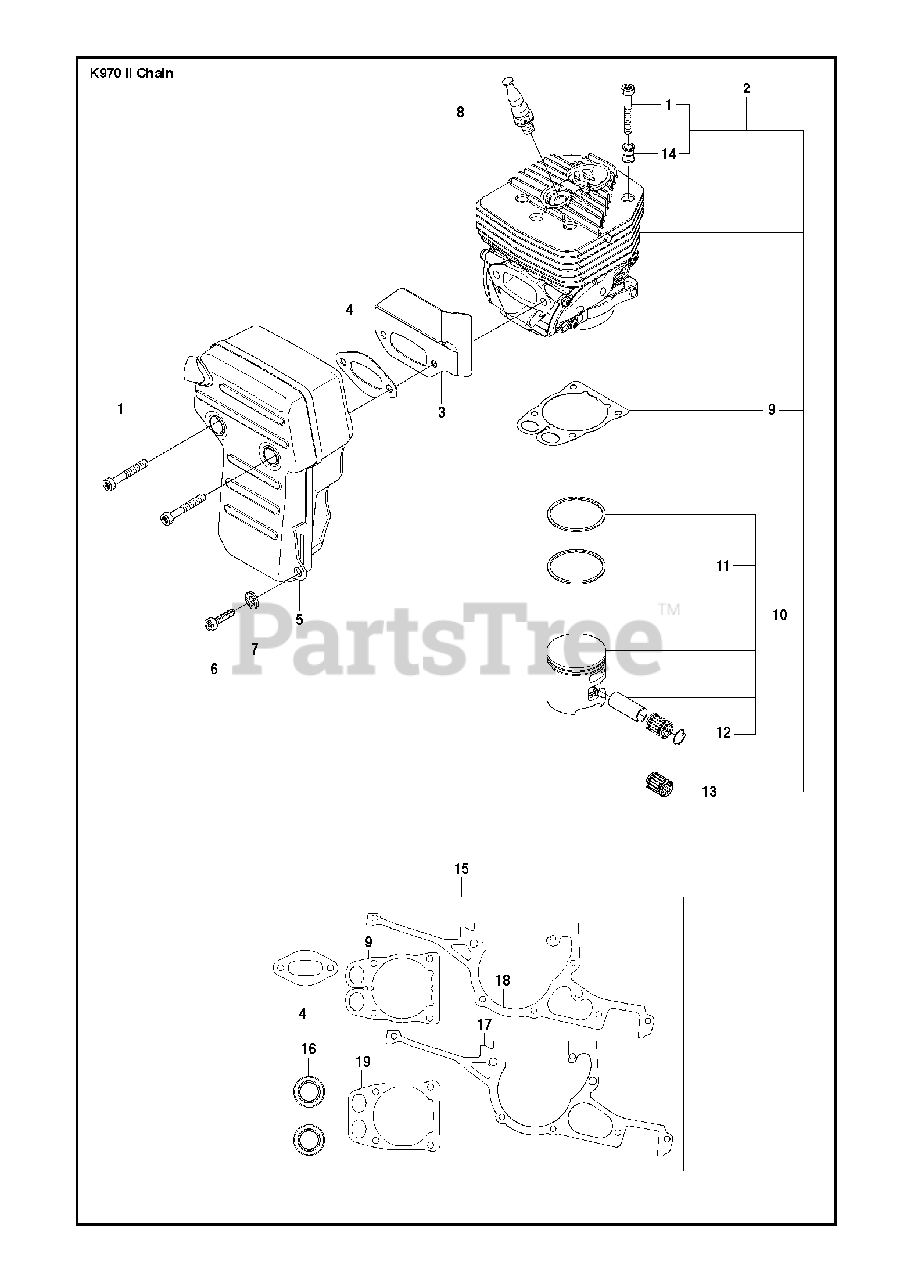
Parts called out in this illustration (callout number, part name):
1	SCREW ITXSCM
2	CYLINDER ASSYIncl. 1, 9, 10, 13, 14
3	HEAT DEFLECTOR
4	GASKET
5	MUFFLER ASSY
6	SCREW ITXSCM
8	DECOMPRESSION VALVE
9	GASKETPaper gasket
10	PISTONIncl. 11, 12
13	NEEDLE BEARING
15	GASKET KITIncl. 4, 9, 16-19
16	SEALING RING
19	GASKETMetal gasket
